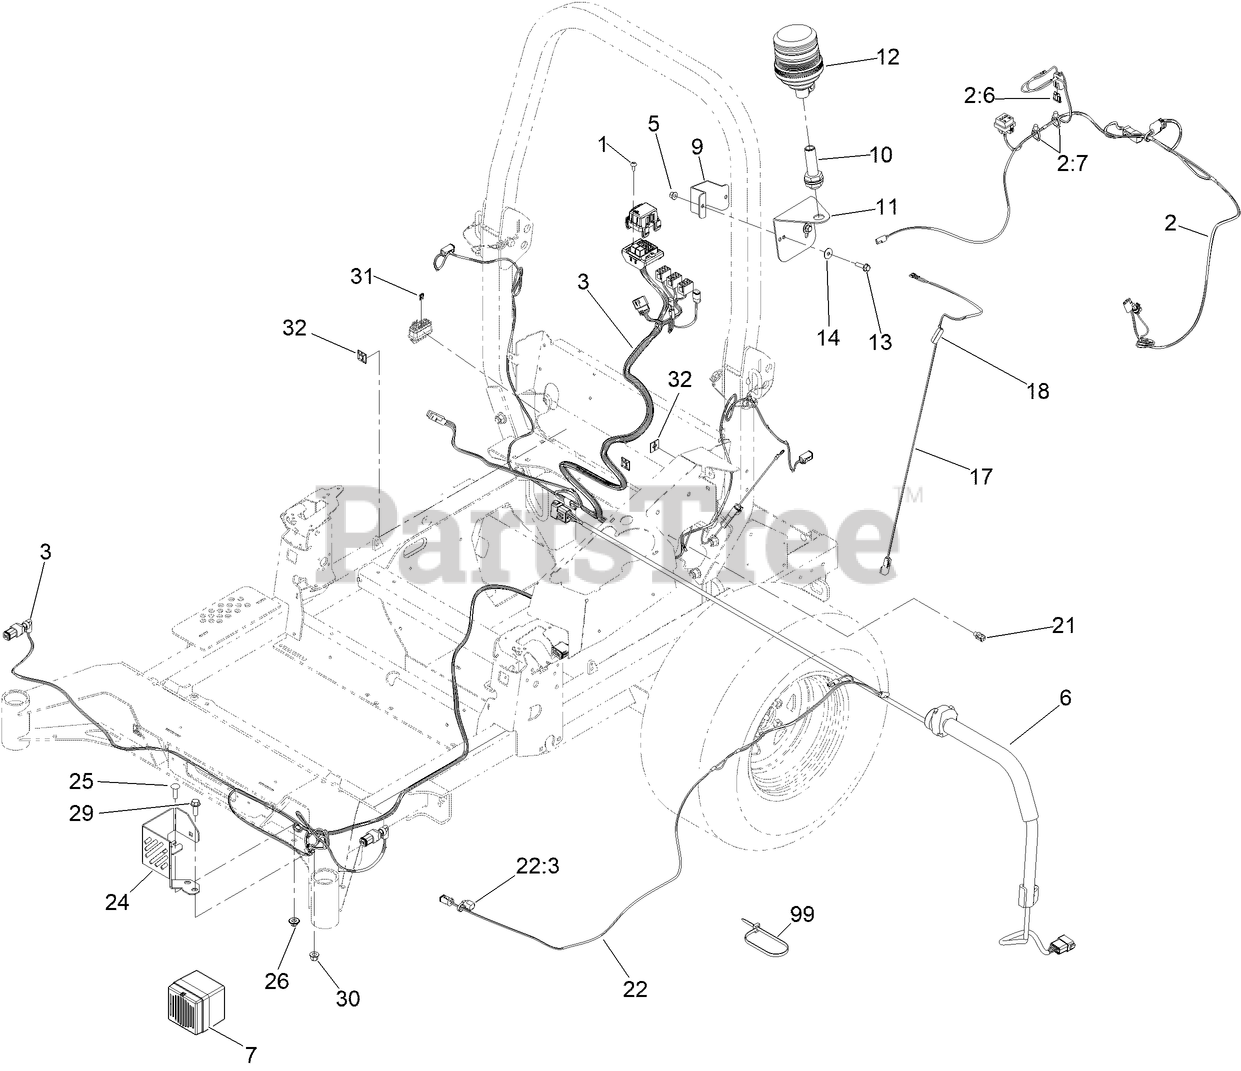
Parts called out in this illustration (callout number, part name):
1	SCREW-SOC, HD
2	HARNESS-WIRE, EU POWER ADAPTOR
2:6	FUSE-BLADE, 7.5 AMP
2:7	CLIP-TIE
3	HARNESS-WIRE, EU LIGHT KIT
5	NUT-FLANGE, NI
6	LEVER ASM-LH
9	CLAMP-50MM
10	SOCKET-BEACON
11	BRACKET,BEACON
12	LIGHT-BEACON ASM
13	SCREW-HHF
14	WASHER-PLAIN
17	HARNESS-WIRE
18	FERRITE, EMC SUPPRESION
21	CLIP-TIE
22	HARNESS-WIRE,WORK LIGHT EXTENSION
22:3	CAP-DUST, 2 WAY
24	BRACKET, HORN
25	SCREW-CARR
26	NUT-FLANGE, NI
29	SCREW-HHF
30	NUT-FLANGE, NI
31	FUSE-MINI BLADE, 7.5 AMP
32	MOUNT-TIE, CABLE
99	TUBE-WRAP, BRAIDED, ORANGE
99	TIE-CABLE
